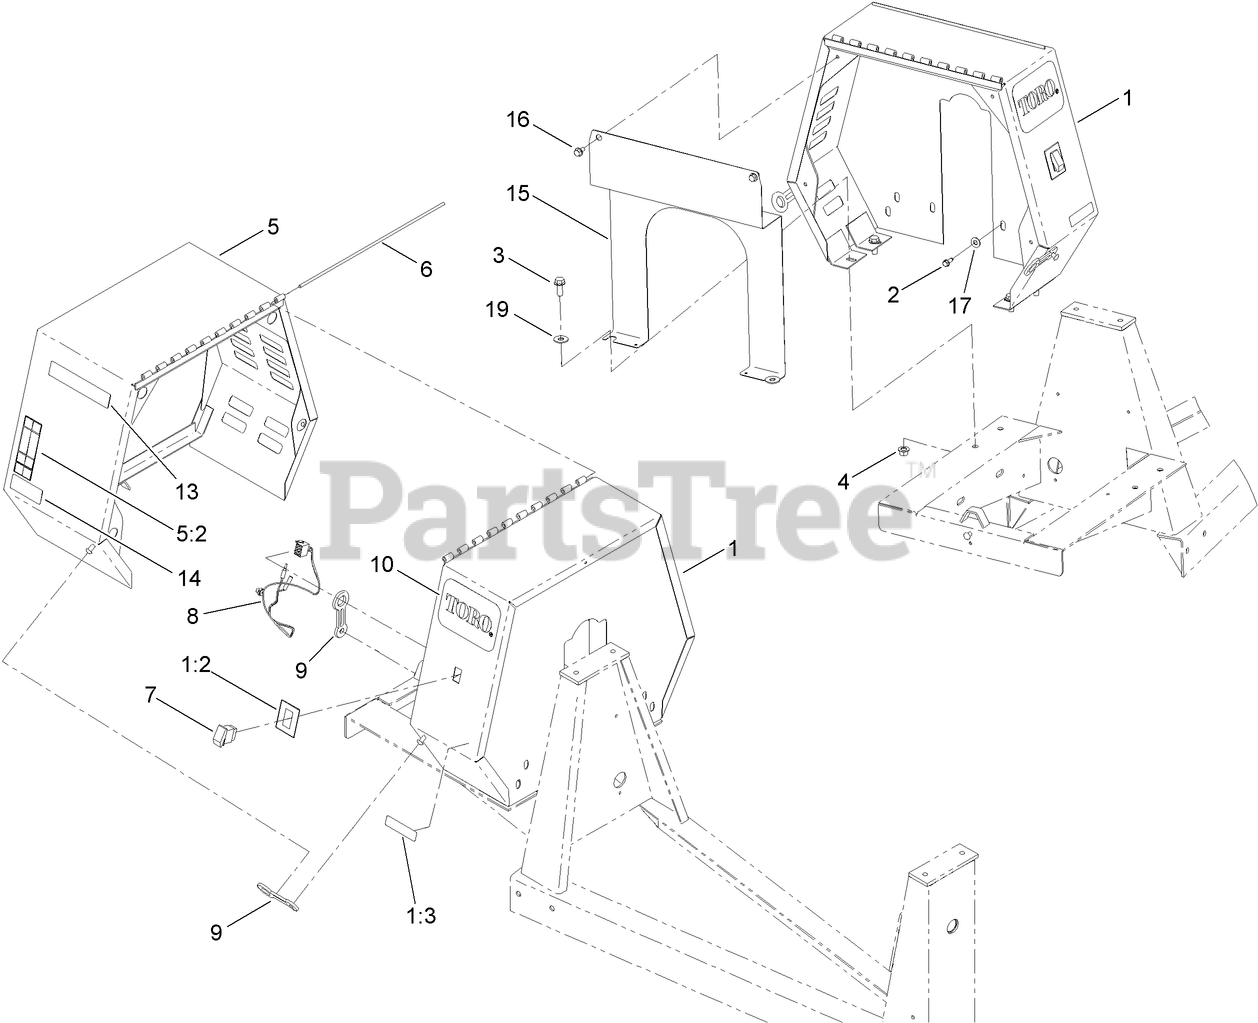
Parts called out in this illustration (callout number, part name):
1	STATIONARY COWL ASM
1:2	DECAL-STOP, ENGINE
1:3	DECAL-ARRESTER, SPARK
2	SCREW-HWHTF
3	SCREW-HHF
4	NUT-LOCK
5	MOVABLE COWL ASM
5:2	DECAL-WARNING
7	SWITCH
8	HARNESS-WIRE, MIXER
9	LATCH-RUBBER
10	DECAL
15	PLATE-ENGINE
16	SCREW-HWH
17	WASHER-FLAT
19	WASHER-FLAT
